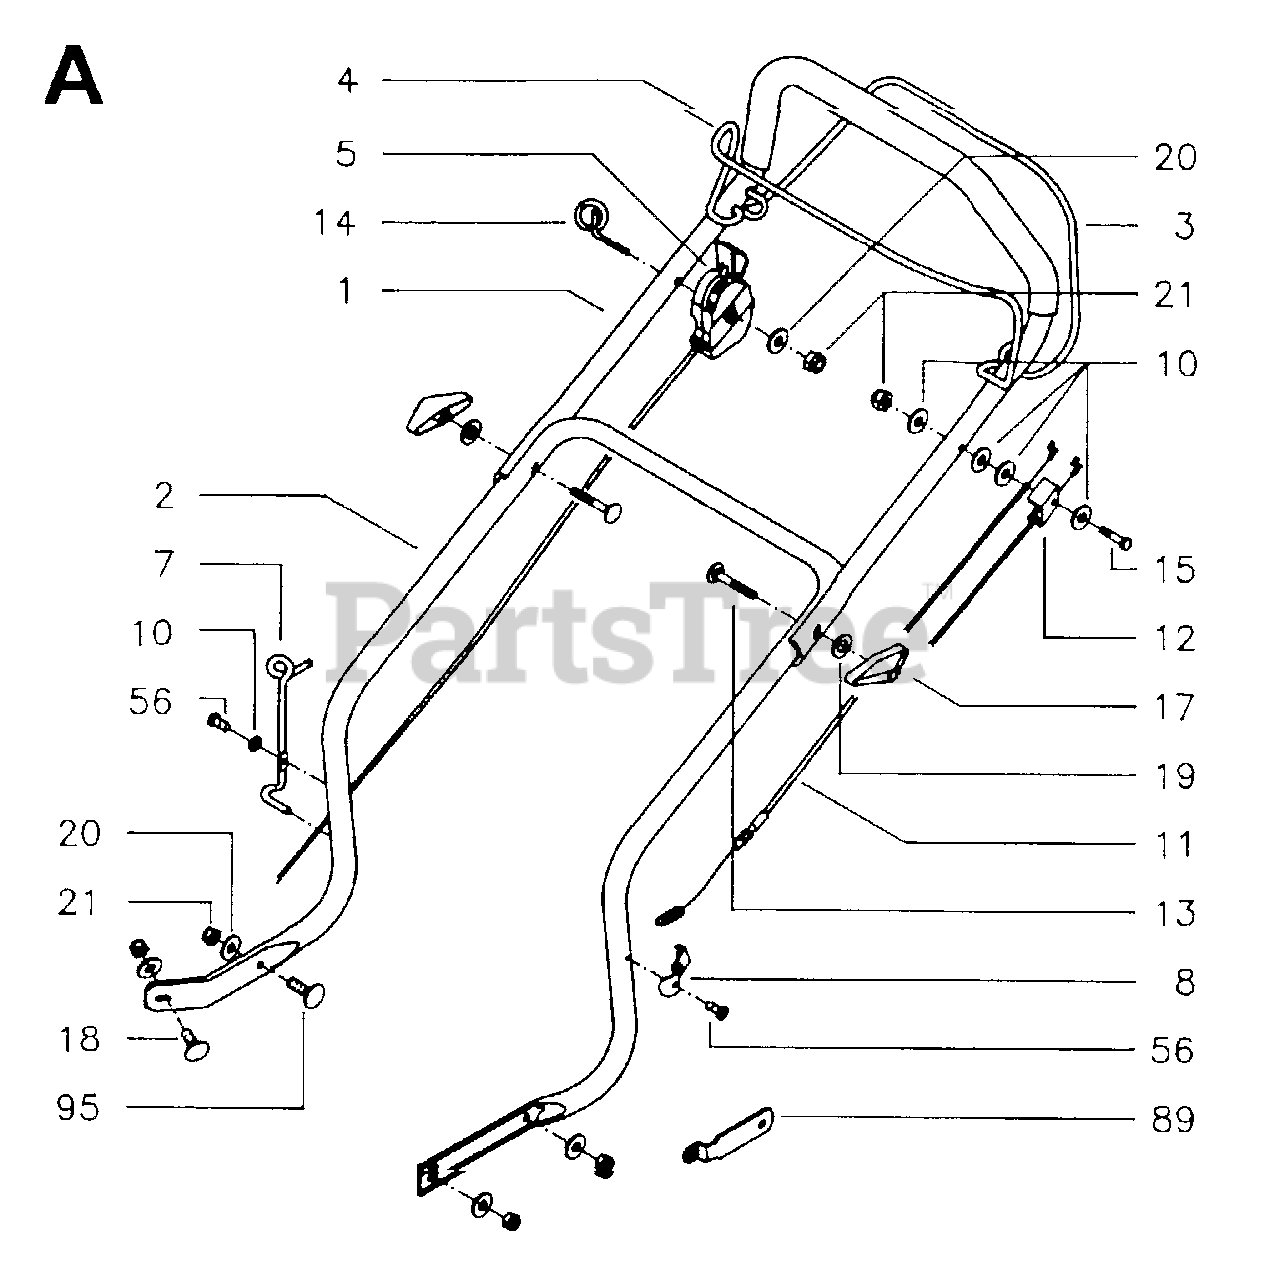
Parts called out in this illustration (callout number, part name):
5	CONTROL
19	WASHER - 15X7.3X1.6
21	LOCKNUT M6
95	REPL BY 515 71 16-20
